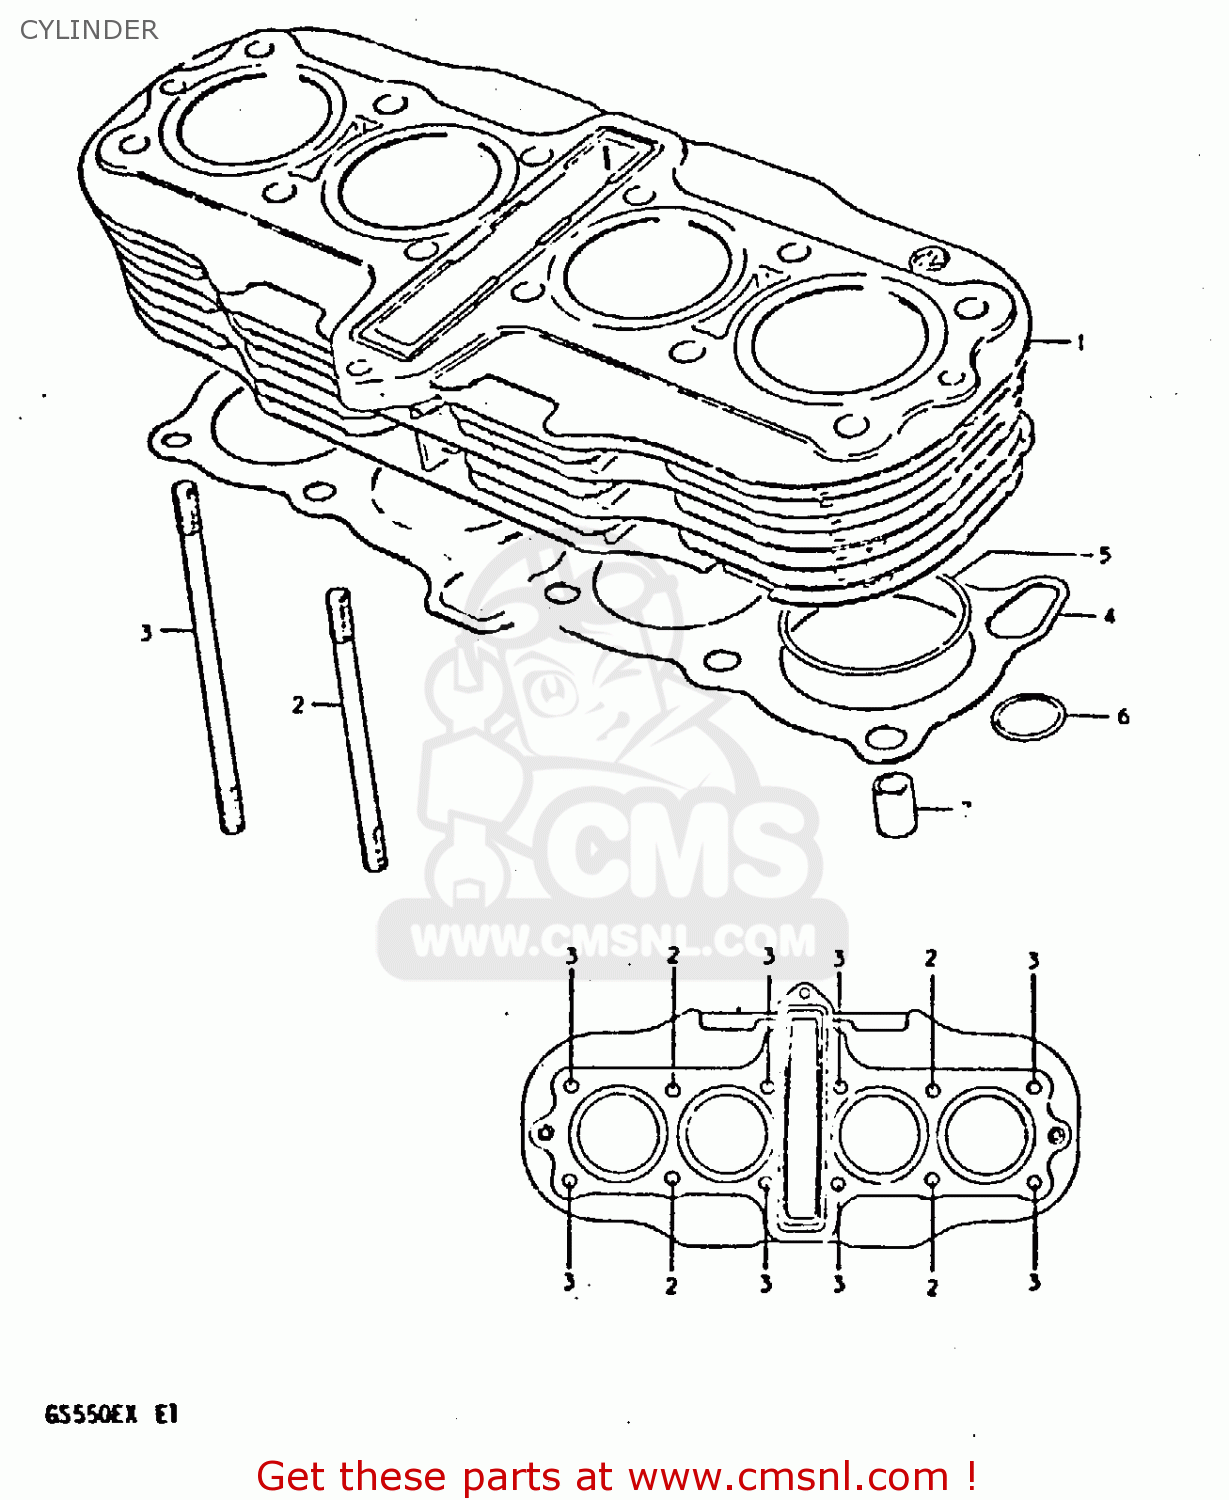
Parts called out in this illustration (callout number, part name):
1	CYLINDER
2	BOLT,STUD
3	BOLT,STUD
4	GASKET,CYLINDER (MCA)
5	O RING(D:2,ID:61)
6	INVALID PARTNUMBER
7	PIN
